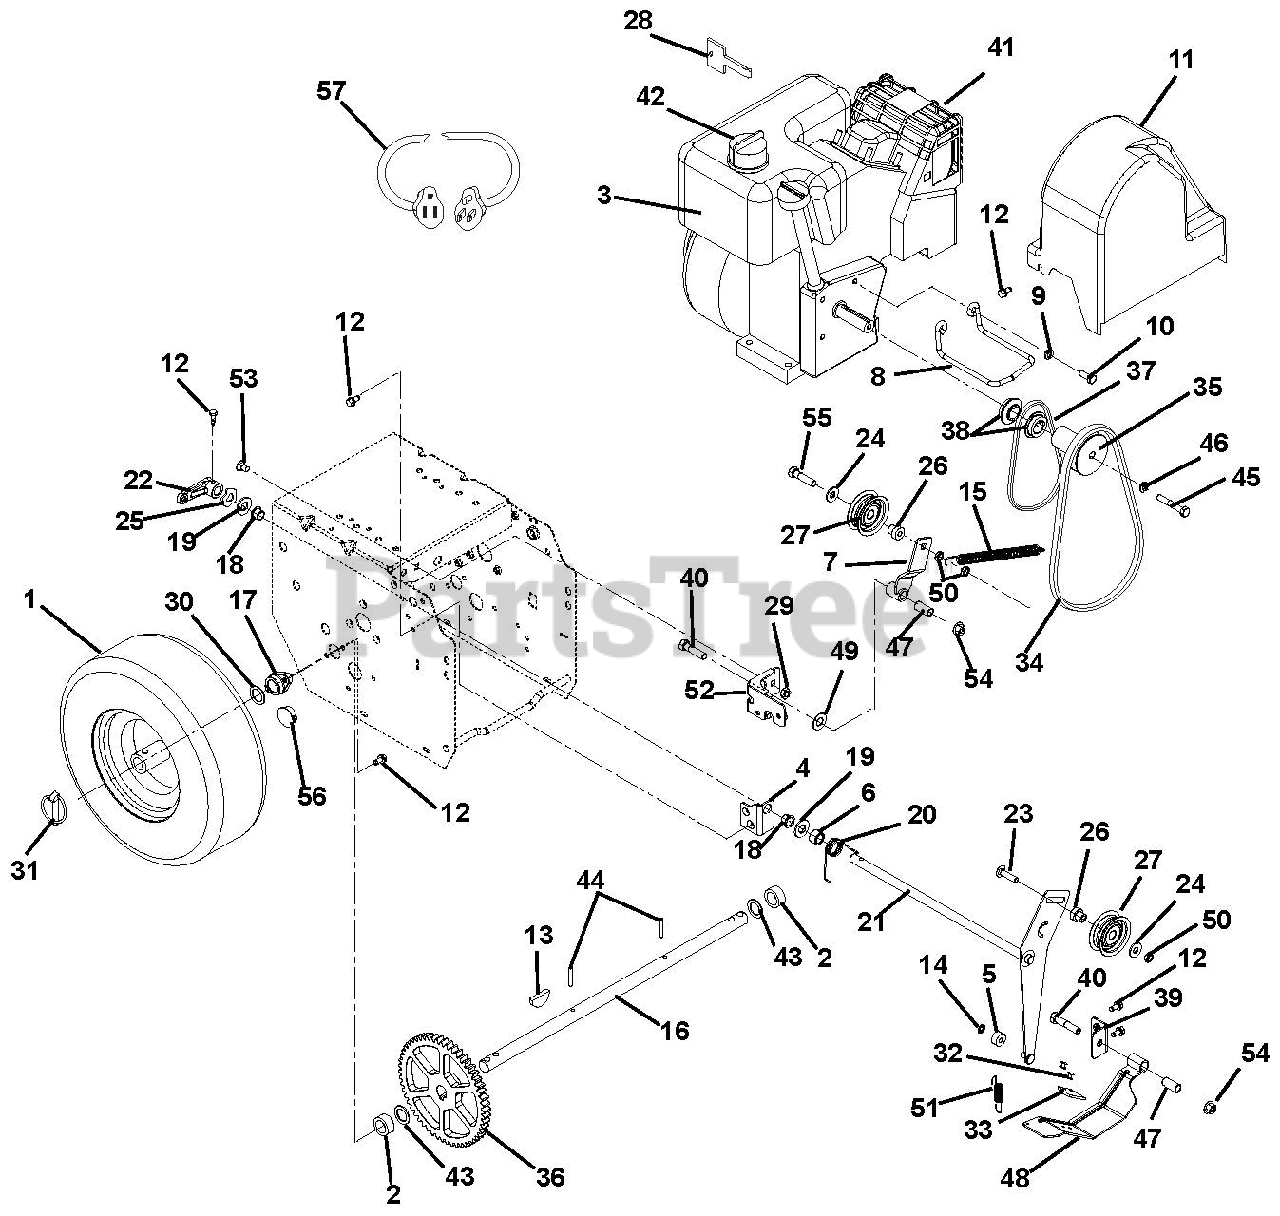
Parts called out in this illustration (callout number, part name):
1	TIRE/WHEEL, RH 4.10-6 PIN K478
1	TIRE/WHEEL, LH 4.10-6 PIN K478
1	TIRE, 4.10-6 K478
2	BSHG-SLV .766 X 1.125 X .500
3	ENGINE, 6HP TEC OHV 120V
3	ENGINE, 7HP TEC OH195SA 120V
3	ENGINE, 5HP TEC LH195SA 120V
3	ENGINE, 5HP TEC OH195SA RECOIL
3	ENGINE, TEC OH195SA 7.0HP RECL
4	BRACKET, MOUNT - IDLER ARM
5	BSHG,SLV .270 X .750 X .250
6	BSHG-SLV .510X.751X.475
7	WELDMENT, TRACTION IDLER ARM
8	FINGER, BELT
9	WSHR-LK .312X.097 HVY YWZC
10	BLT-HEX .31-24X.75 YWZC GR5
11	COVER, BELT
12	@SCR-TAP .25-20X.50 HWH TR YWZ
13	KEY-WDRF .25X.750X.313 SAE91
14	RG-RTNG-EXT .250X.010
15	SG-TENS .062X.56X8.0 WLD 11
16	SHAFT, AXLE
17	BSHG .75X1.125X.65
18	BUSHING, POLYLINER-.50 SPLIT
19	@WSHR-FL-STL.531X1.06X.095YWZC
20	SG-TORS .075 X .955
21	WELDMENT, ATTACHMENT IDLER ARM
22	ARM, CLUTCH - ATTACHMENT
23	@BLT-RHDSHSQNK.31-18X1.25 G5YZ
24	@WSHR-FL-STL.38X.875X.083 YWZC
25	WSHR-WAVE .50X.75X.015 .13FRHT
26	SPCR, BRG .315X.50X.688X.281
27	IDLER
28	KEY, PUSH/PULL - TECUMSEH
29	@NUT-LK-TOP-FLG .31-18 YWZC
30	WSHR-FL-STL.754X1.125X.062YWZC
31	PIN-LOK .31X1.75
32	RVT-POP .187 YZ
33	PAD, BRAKE
34	V-BELT, HA-RAW EDGE
35	SHEAVE, ATTACHMENT DRIVE
36	SPUR GEAR, 54T .75ID X 6.75PD
37	V-BELT, 3L-WRAPPED
38	TRACTION SHEAVE HALF
39	BRACKET, MOUNT - BRAKE
40	@BLT-HEX .38-16X1.75 GR5 YWZC
41	PLUG, SPARK
42	CAP, FUEL - TECUMSEH
43	WSHR-FL-STL.754X1.125X.062YWZC
44	PIN-ROLL .188X1.25
45	BLT-HEX .31-24X2.00 GR5
46	WSHR-LK .312X.097 HVY YWZC
47	BSHG-SLV .385X.500X1.045
48	BRAKE ARM W/PAD
49	@WSHR-FL-STL.406X.812X.065 YWZ
50	@NUT-LK-CTR-JAM .31-18 YWZC
51	SPRING-EXT .437 X .438 X 2.64
52	WELDMENT, FRAME BRACKET
53	@BLT-RHDSSQNK .31-18X.62 G5YZ
54	@NUT-LK-TOP-FLG .38-16 YWZC
55	@BLT-HEX .31-18X1.50 GR5 YWZC
56	PLUG, HOLE - 1.00" NYLON
57	CORD, ELECTRIC START CORD 120V
